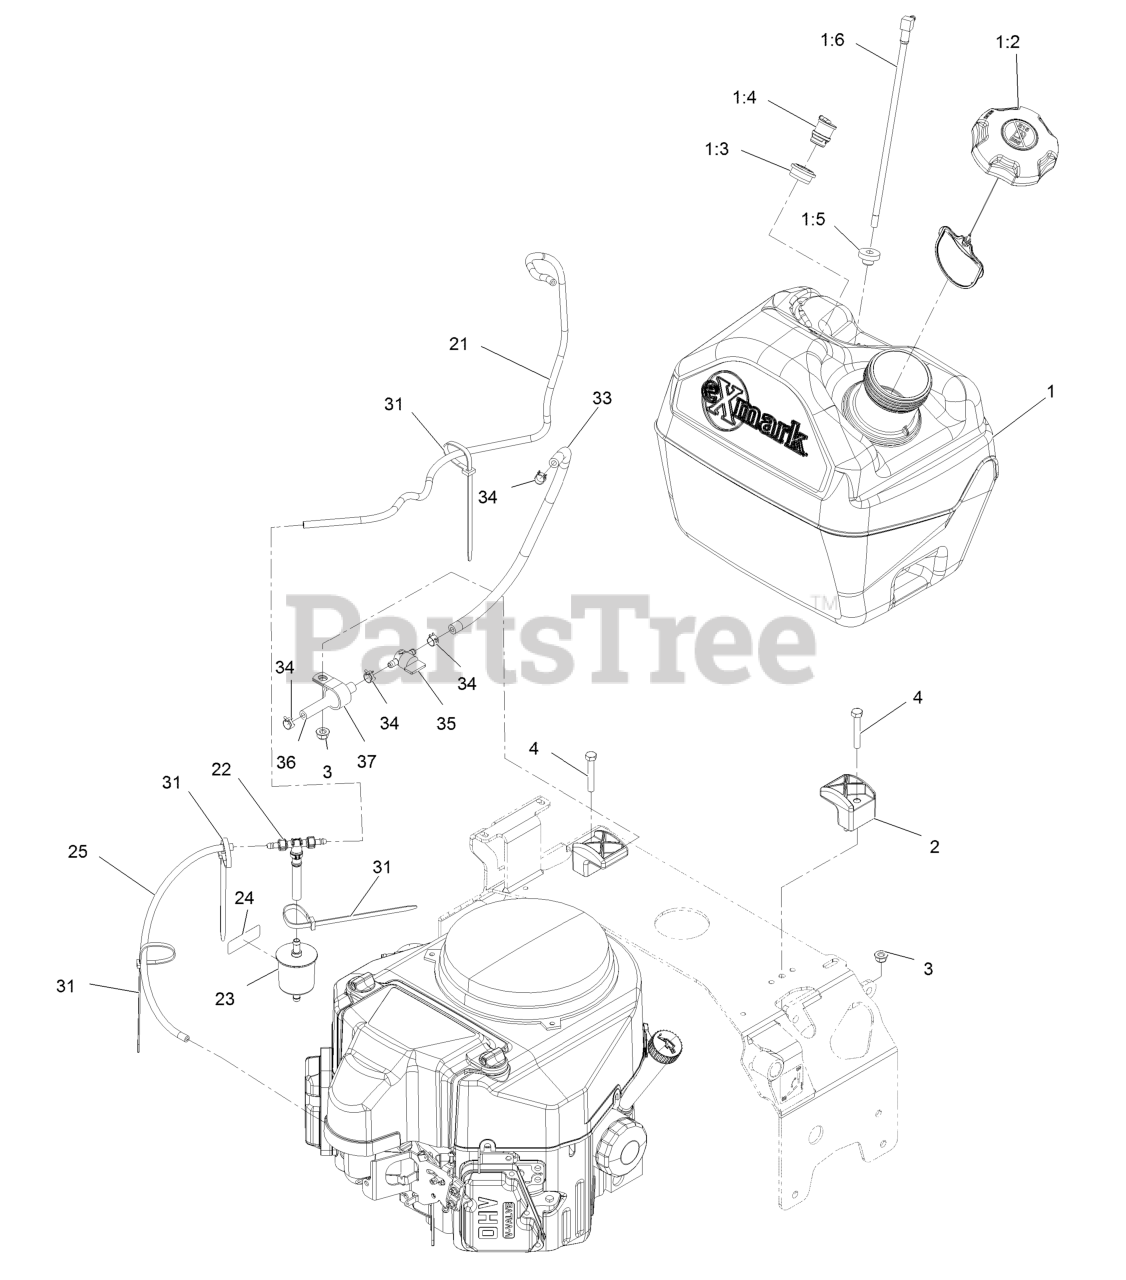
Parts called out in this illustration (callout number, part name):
1	ASM, Fuel Tank 5 Gal
1:2	Cap-Fuel, Ratcheting
1:3	Grommet
1:4	Valve-Vent, Fuel
1:5	Bushing
1:6	Fitting-Fuel (W/Line And Screen)
3	Nut-Nyloc 5/16-18 Flg
4	Screw-HH 5/16-18 X 2
21	Hose, Emissions
22	Tee And Check
23	Filter-Fuel
24	Decal-Filter, Emissions
25	Hose-Fuel
31	Tie-Cable 7 15/16 (Large)
33	Hose-Fuel
34	Clamp-Hose
35	Valve-Fuel
36	Hose-Fuel
37	Clip-Loom
